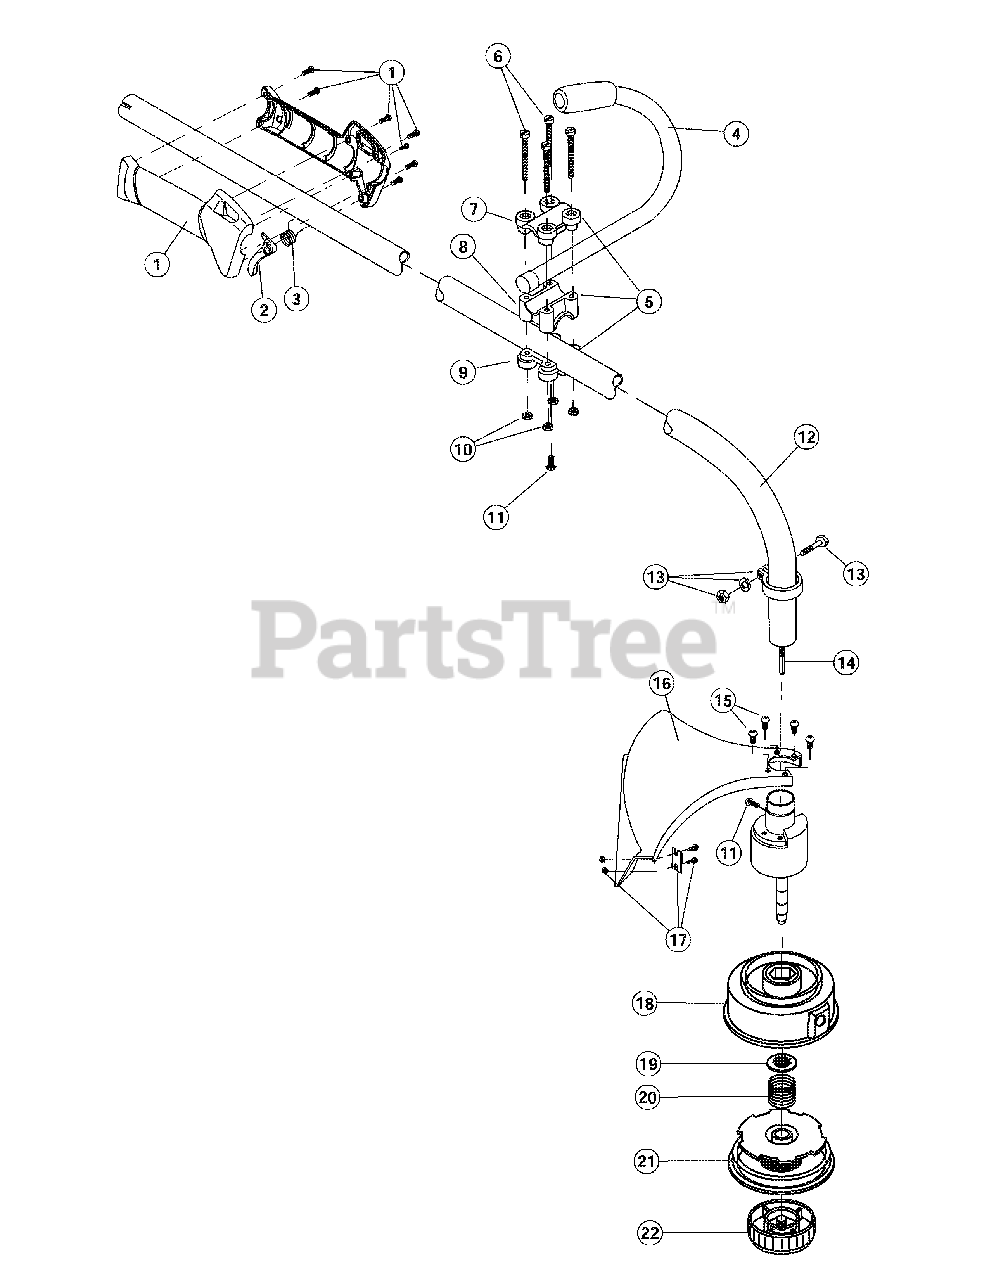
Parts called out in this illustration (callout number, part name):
1	Throttle Housing Assembly (includes 2 & 3)
2	Throttle Trigger
3	Throttle Trigger Spring
4	J-Handle Assembly
5	Handle Bracket Assembly (includes 6-11)
7	Upper Handle Clamp
8	Middle Handle Clamp
9	Lower Handle Clamp
11	Anti-Rotation Screw
12	Drive Shaft Housing Assembly (includes 14)
13	Lower Clamp Assembly (includes 11)
14	Flexible Drive Shaft
15	Guard Mounting Screw
16	Guard (includes 13)
17	Blade Assembly
18	Outer Reel Assembly (includes 16)
19	Retainer
21	Inner Reel
22	Bump Knob
